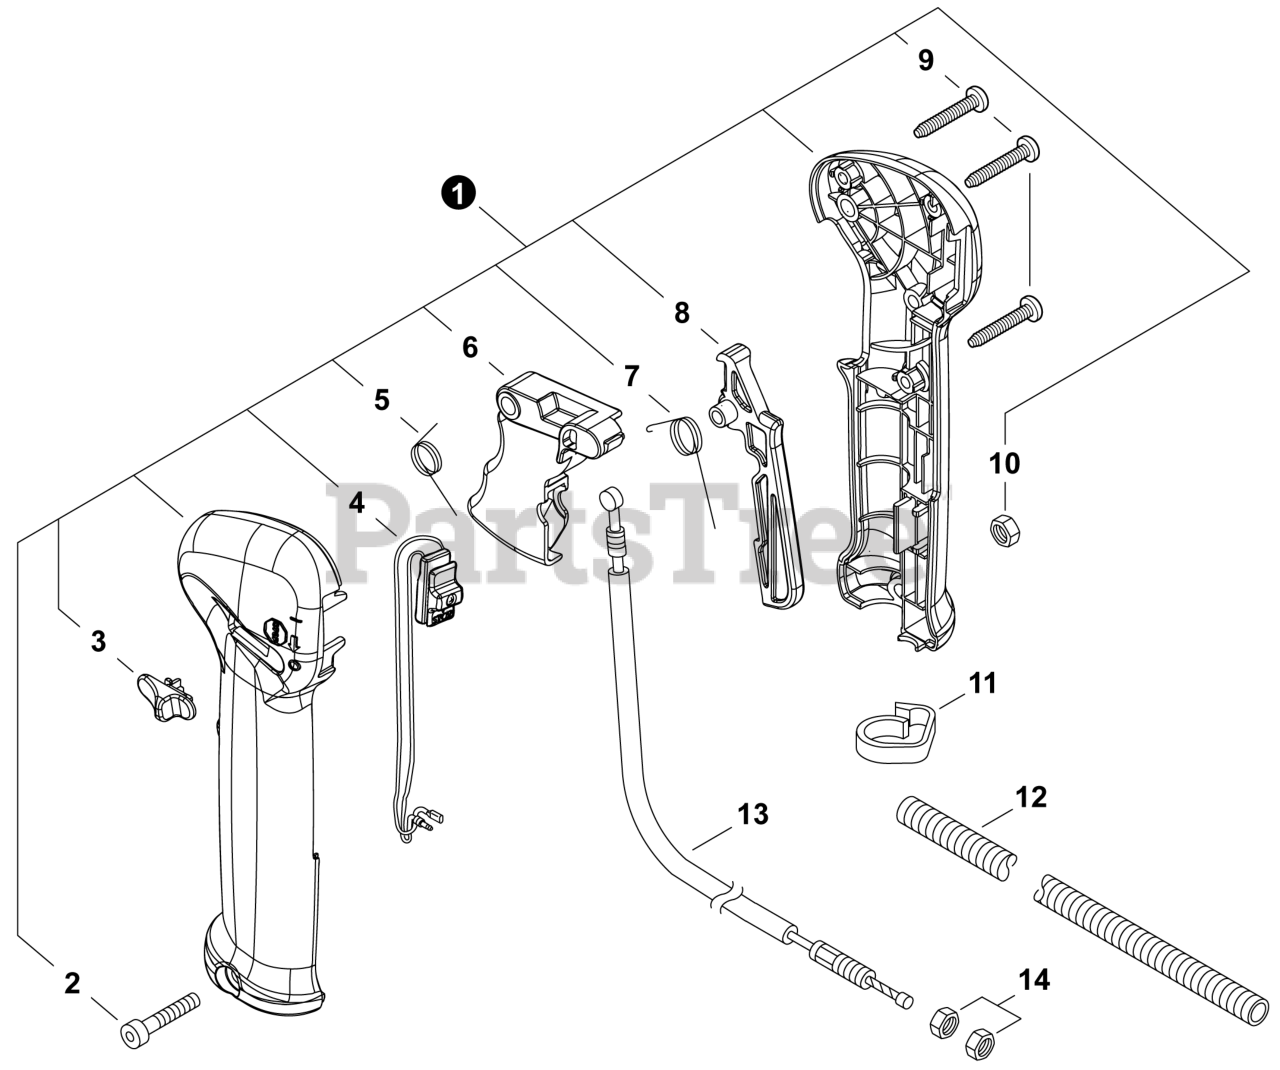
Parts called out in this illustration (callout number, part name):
1	CONTROL HANDLE ASSY
2	BOLT - 5x30
3	LATCH, THROTTLE
4	SWITCH, ON-OFF
5	SPRING, TORSION
6	CONTROL, THROTTLE
7	SPRING, TORSION
8	LOCKOUT, THROTTLE
9	SCREW 4x16
11	CLIP, CABLE
12	TUBE, FLEXIBLE
13	CABLE, THROTTLE
